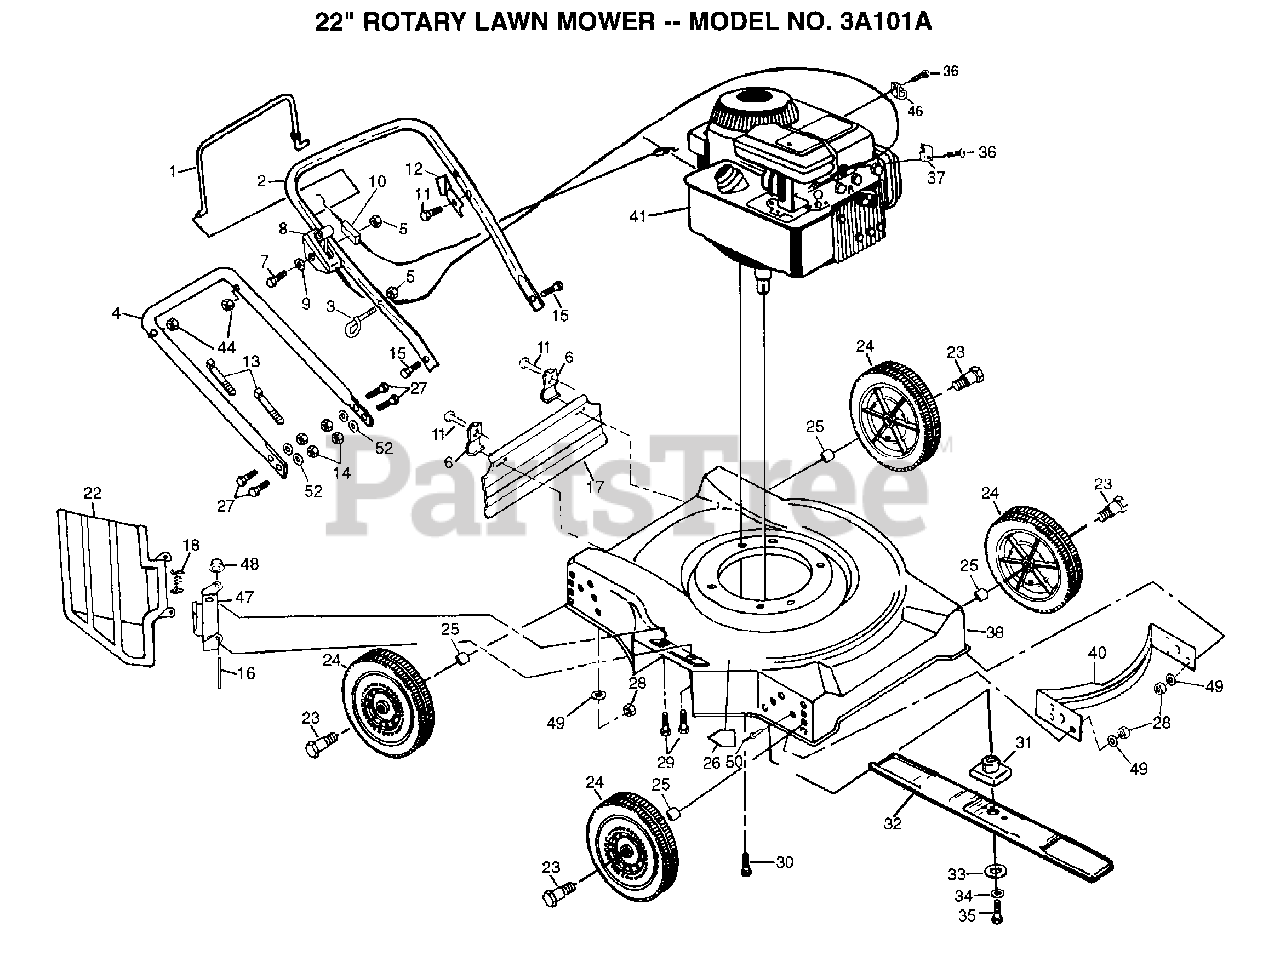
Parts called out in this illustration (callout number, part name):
1	CONTROL BAR PM
2	UPPER HANDLE
3	ROPE GUIDE
4	HANDLE LWR PM
6	"BRKT,DEFL PM"
9	WASHER PM
10	CABLE.ZONE.CONTRO
11	TAPPING SCREW
12	"BRKT,UPSTOP"
14	LOCKNUT
15	BOLT 1/4-20-1 1/2
16	"ROD,HINGE "
18	"SPRING,TORSION"
23	AXLE BOLT
24	WHEEL&TIRE
26	DECAL HYT
28	LOCKNUT PM
29	SCREW
30	SCREW
31	BLADE ADAPTOR
32	"BLADE.22"""
33	"WASHER,HARDEN"
34	LOCKWASHER
35	SCREW
36	SCREW PM
37	CABLE CLAMP
38	KIT.HSG.22SD
46	"CLIP,CABLE"
47	"BRKT,HSG"
48	PUSH ON SPEED NUT
50	BLIND RIVET
52	STEEL WASHER
